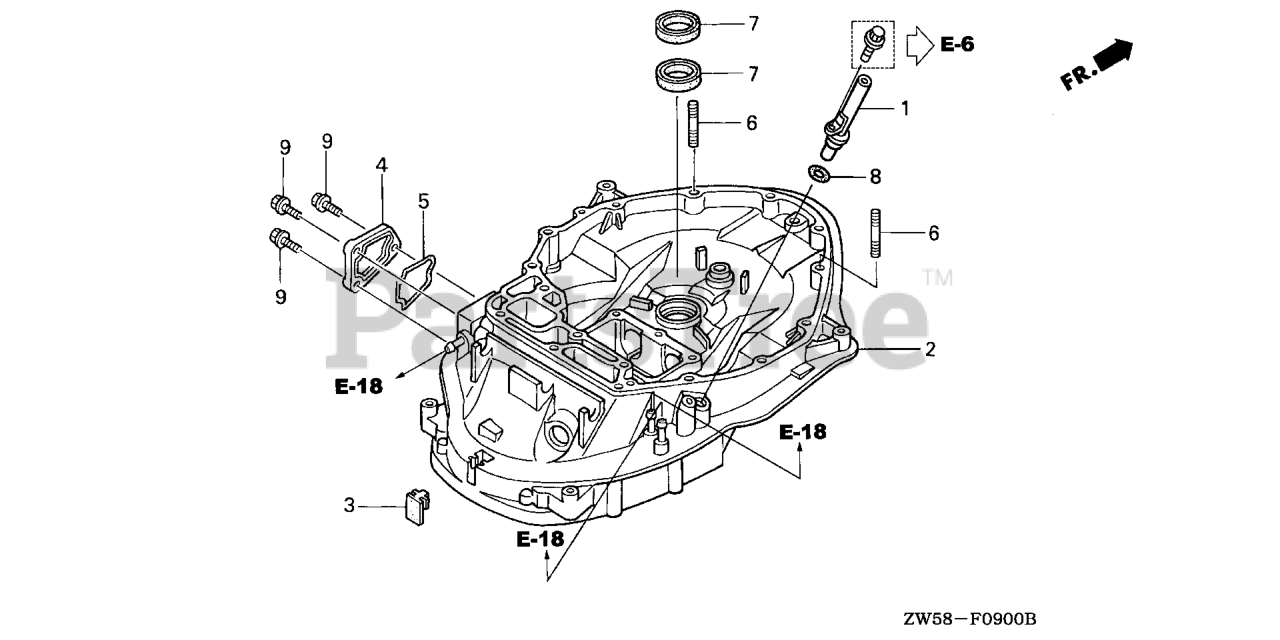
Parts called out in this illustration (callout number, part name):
1	PIPE, OIL LEVEL
2	CASE, MOUNT *NH8* (DARK GRAY)
3	RUBBER, MOUNT CASE SEAL
4	COVER, MOUNT CASE *NH8* (DARK GRAY)
5	GASKET, MOUNT CASE COVER
6	BOLT, STUD (10X35)
7	SEAL, WATER (22X35X7)
8	O-RING (11.5X3.5)
9	BOLT, FLANGE (6X20)
